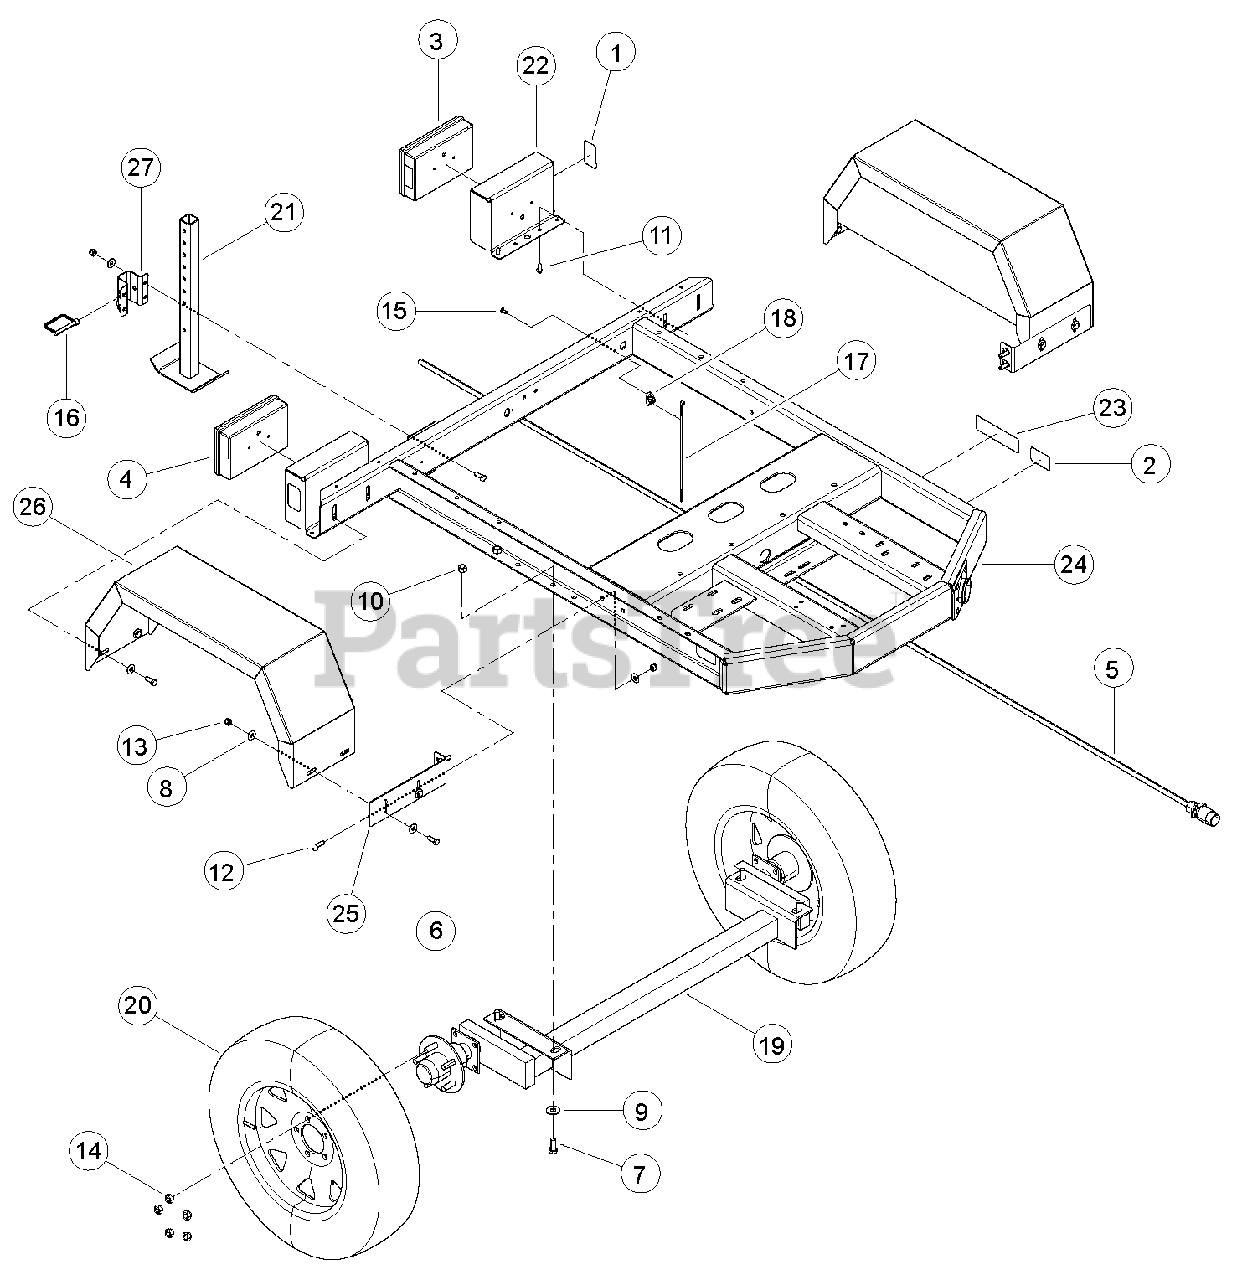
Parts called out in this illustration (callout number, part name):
1	REFLECTOR, WIDE ANGLE RED
2	REFLECTOR, WIDE ANGLE AMBER
3	LIGHT, TAIL RH
4	LIGHT, TAIL LH
5	HARNESS, TRAILER LIGHTING
6	BOLT, 3/8 X 1 HEX HD GR5 ZP
7	BOLT, 1/2 X 1-1/4 HHCS NC ZP
8	WASHER, 3/8 FLAT ZP
9	WASHER, 1/2 FLAT ZP
10	NUT, 1/2 CENTERLOCK GRB ZP
11	SCREW, 11/32 X 7/8 HWH AB THREAD ZP
12	BOLT, 3/8 X 1-1/4 CRG GR5 NC ZP
13	NUT, 3/8 NE NYLOCK ZP
14	BOLT, 1/2-20 WHEEL LUG
15	RIVET, AL BLIND 1/4 X 3/4 DOME HEAD
16	PIN, 3/8 X 2-3/4 SNAP
17	STRAP, 11 IN. BLACK TIE
18	CLAMP, CABLE MOUNT
19	AXLE, DURA-FLEX TORSION 1800
20	ASSY', TIRE AND WHEEL 14 IN.
21	WELDMENT, REAR STABILIZER
22	BRACKET, TAIL LIGHT
23	TAG, VIN
24	WELDMENT, CHIPPER TRAILER
25	BRACKET, FENDER
26	WELDMENT, CHIPPER FENDER
27	GUIDE, TRAILER SUPPORT [WAS 76652-12]
